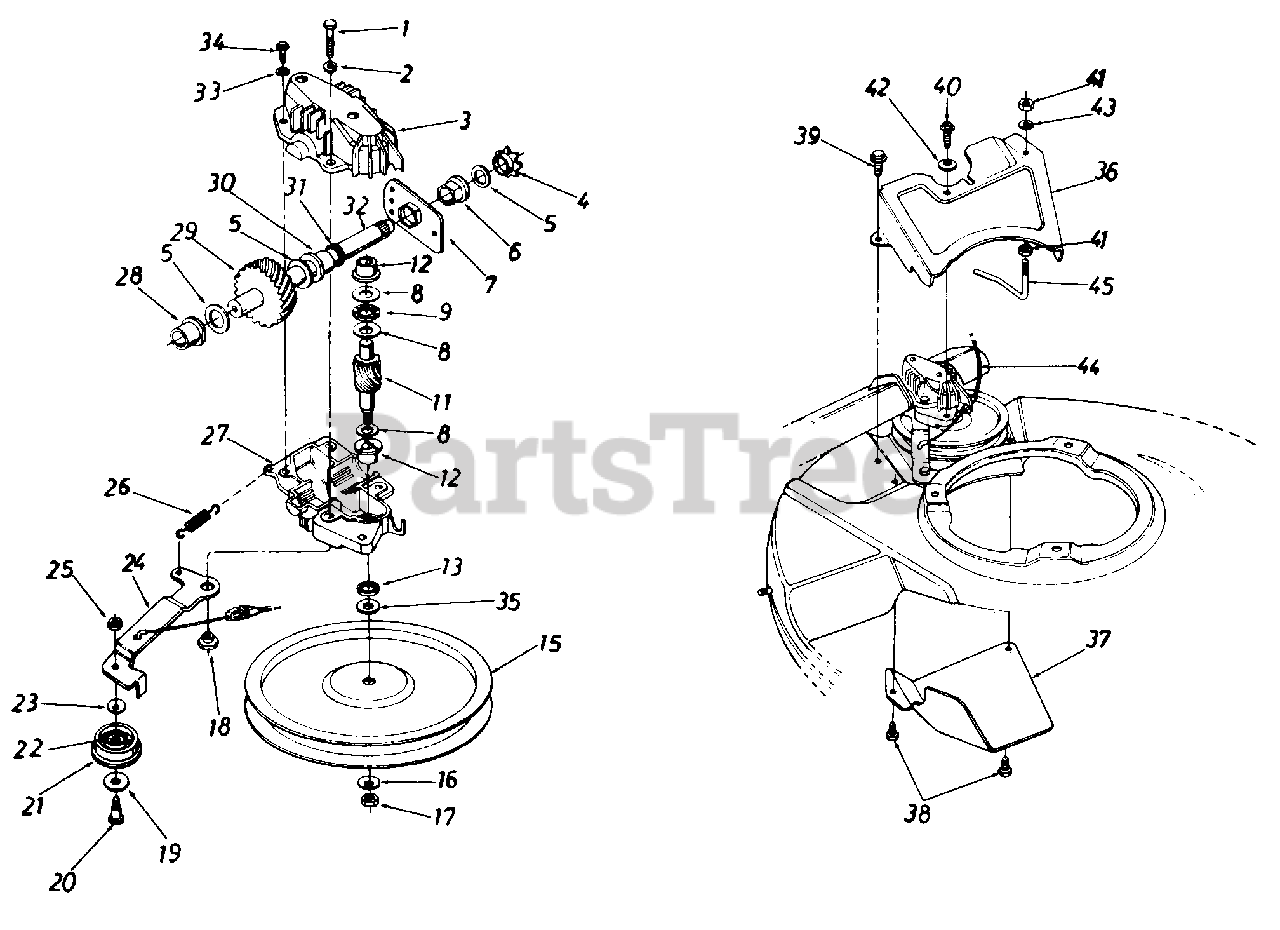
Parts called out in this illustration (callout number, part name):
1	Hex Bolt 1/4-20 x 1.25" Lg. w/Patch
2	L-Wash. 1/4" I.D.
3	Upper Hsg. Half
4	#48 Sprocket 7 Tooth x 1/2 Pitch
5	Fl-Wash. 5/8" I.D. x .030
6	Hex Flange Brg. .631" I.D.
8	Thrust Wash. .382" I.D. x .70" O.D.
9	Thrust Bearing .375" I.D. x .812" O.D.
11	11 Tooth Helical Gear
12	Flange Bearing
15	Fl-Pulley 5.06" I.D.
16	Bell-Wash. .265" I.D. x .75"
17	Hex Nut 1/4-28 L.H. Thd.
18	Shld. Spacer .375" Dia. x .170
19	Fl-Wash. .390" I.D. x 1.0"
20	Shld. Bolt .375" Dia. x .40"
21	Fl-Idler Plastic 1.50" Dia.
22	Needle Brg. .375" x .31"
23	Bell-Wash. .265" I.D. x 75"
24	Idler Brk't. Ass'y
25	Hex Patch L-Nut 1/4-28 Thd.
26	Extension Spring 1.12" Lg.
27	Lower Hsg. Half
28	Flange Bearing .56 Dia.
29	33 Tooth Helical Gear
30	Flange Bearing .629 Dia.
31	Oil Seal .625 Dia.
32	Gear Sprocket Shaft
33	L-Wash. #10 I.D.
34	Hex B-Tap Scr. #10 x .62"
35	Hex Washer .26" x .88"
39	Hex AB-Tap Scr. 1/4 x .50" Lg
40	Hex B-Tap Scr. 1/4 x .62" Lg.
41	Hex Nut 1/4-20 Thd.*
42	Bell-Wash. .265" I.D. x 75"
43	L-Wash. 1/4" I.D.*
44	S.P. Cable-48" Lg.
45	S.P. Belt Guard
